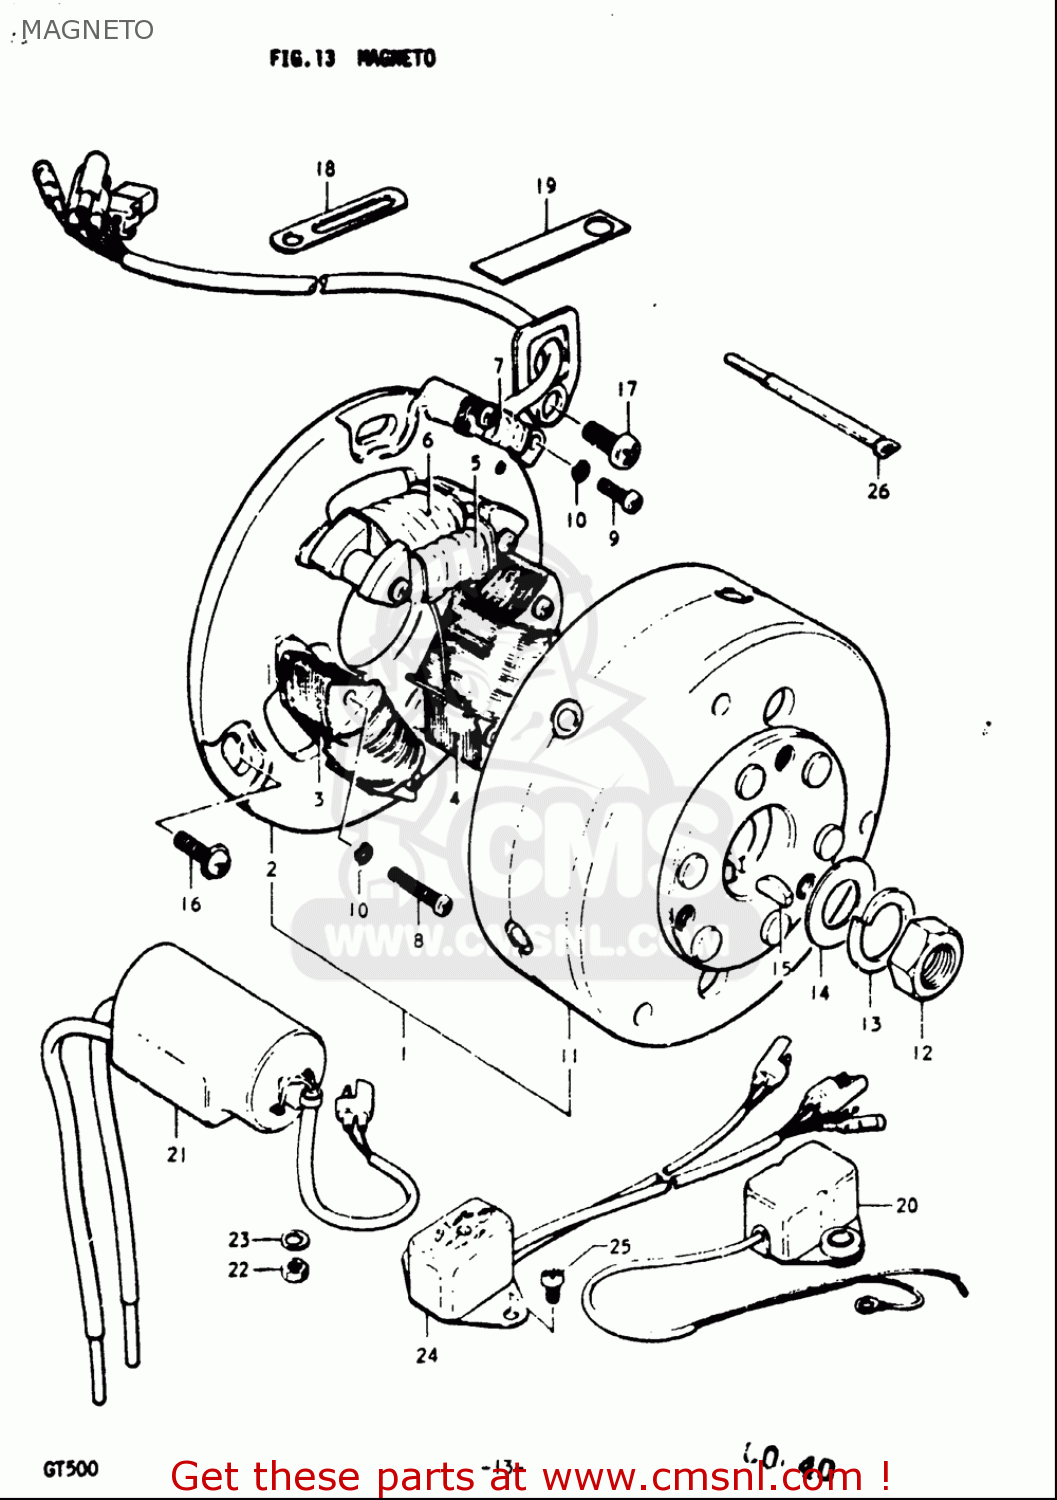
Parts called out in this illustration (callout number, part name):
3	COIL ASSY,CHARGING NO.1
4	COIL ASSY,CHARGING NO.1
5	COIL ASSY,PRIMARY NO.1
6	COIL ASSY,PRIMARY NO.2
7	COIL,PULSER
8	SCREW
9	SCREW
10	WASHER,LOCK
12	NUT
13	WASHER,LOCK
14	WASHER
15	KEY
16	SCREW(5X14)
17	SCREW
18	CLAMP(L:65)
19	CLAMP(L:120 T:1.0)
21	COIL ASSY,IGNITION
22	NUT
23	WASHER
24	CDI UNIT
25	SCREW
26	CLAMP
